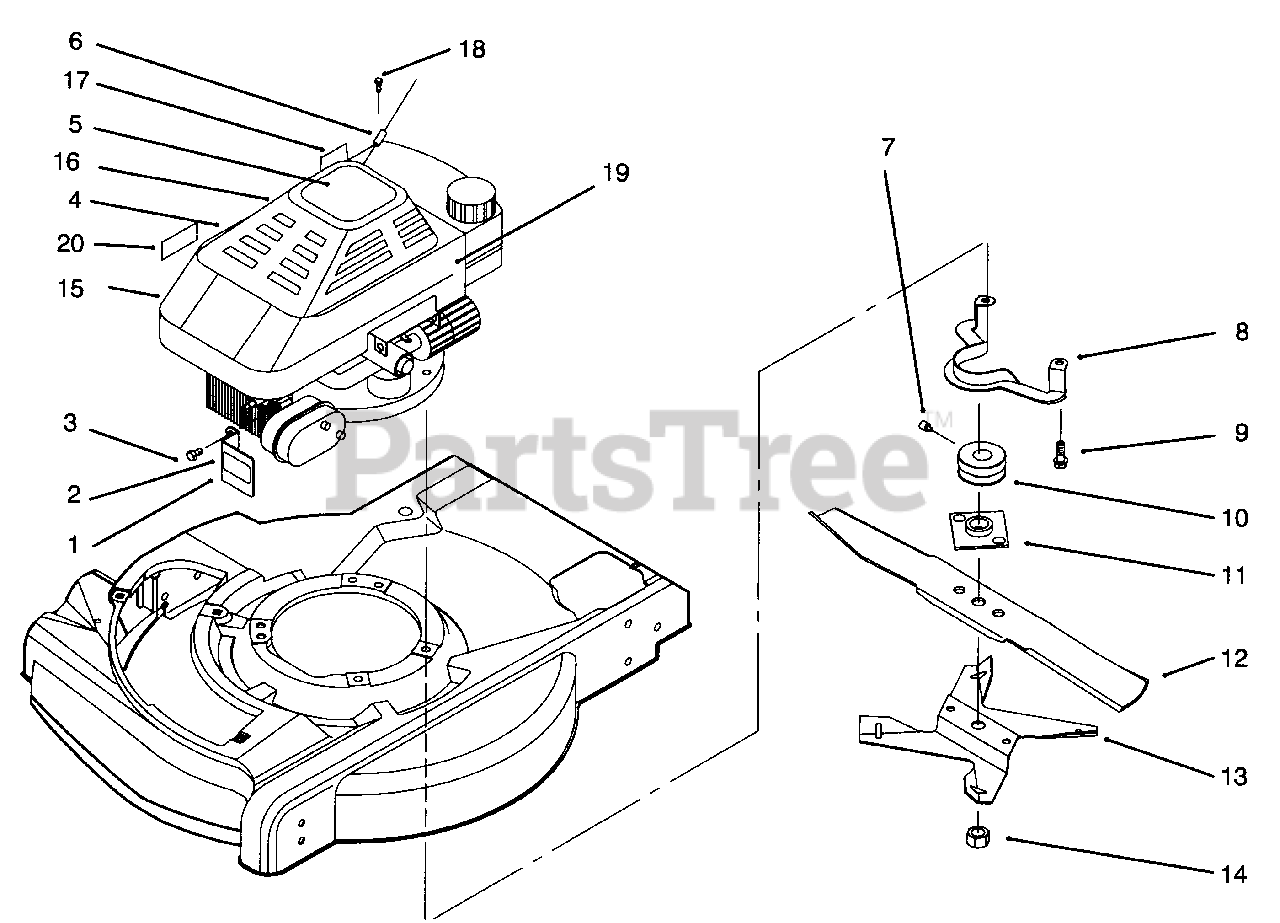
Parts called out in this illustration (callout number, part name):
1	Guard-Muffler (Incl. Ref.#2)
2	Decal-Warning
4	Engine-4 Cycle
5	Decal-Shroud (Hand Push)
6	Stop-Rope
7	Screw-Set
8	Guide-Belt
9	Screw-Engine Mount
10	Pulley-Engine
11	Plate & Collar Ass'y
12	Blade-21"
13	Fan-Mulching
14	Nut-Blade
15	Shroud-Engine
16	Cover-Recoil
17	Decal-Oil
19	Shroud
20	Decal-Oil
